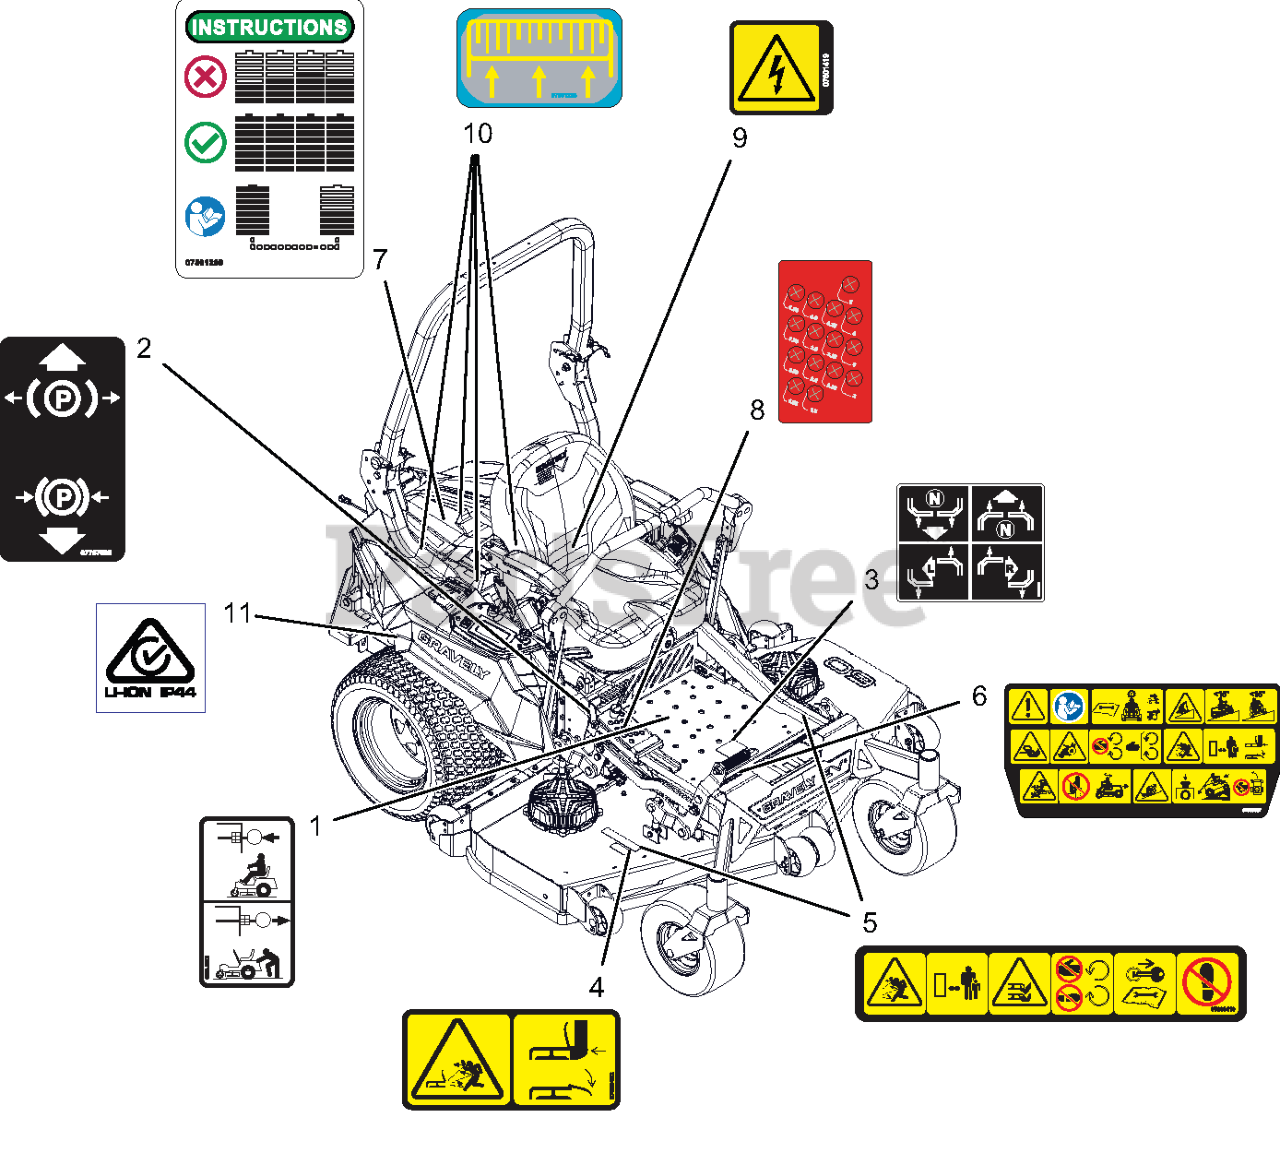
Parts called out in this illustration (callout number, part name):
1	DECAL, TRANSMISSION DISCONNECT
2	DECAL, PARKING BRAKE LEVER
3	DECAL, INSTRUCTIONAL-STEERING
4	DECAL, SAFETY - DECK GUARDING
5	DECAL, DECK SAFETY
6	DECAL, MAIN SAFETY
7	DECAL, BATTERY BALANCE
8	DECAL, HEIGHT OF CUT
9	DECAL, SAFETY - DANGER
10	DECAL, BATTERY INSTALL DIRECTION
11	DECAL, LI-ION IP44
